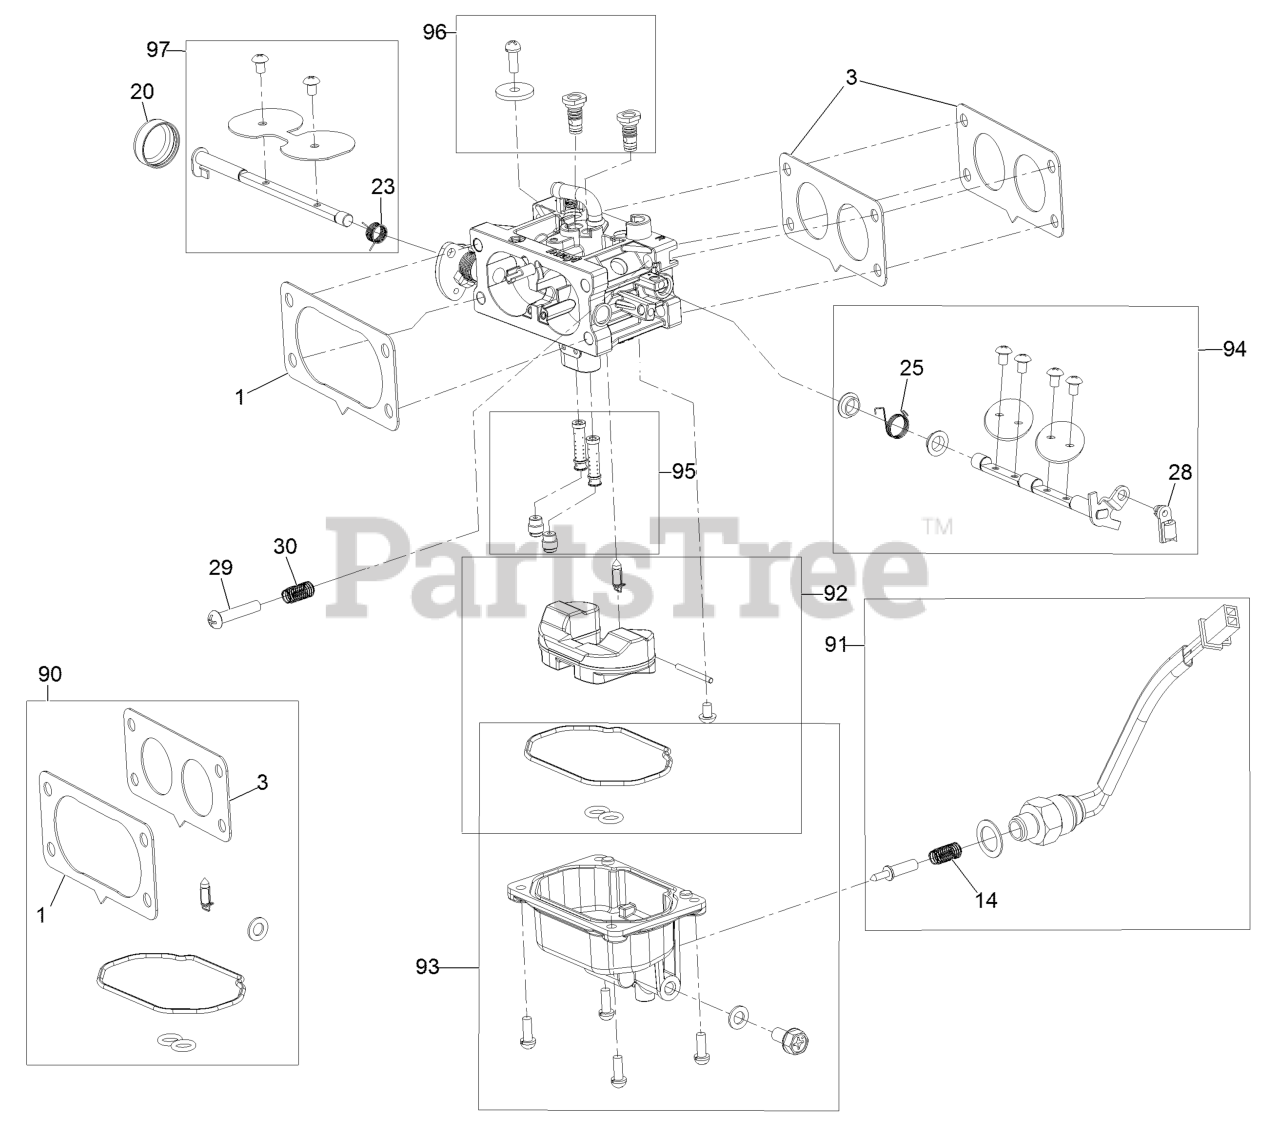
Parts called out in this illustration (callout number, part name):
1	Filter-Fuel
2	Clamp-Fuel Line
3	Line-Fuel
4	Pump-Fuel
5	Screw-HHF
6	Hose-Fuel
7	Hose-Fuel
8	Gasket-Intake
9	Screw-HHF
10	Manifold-Intake
12	Gasket-Carburetor
13	Insulator-Carburetor
14	Linkage-Throttle
96	Carburetor Replacement Kit
96:1	Carburetor
96:2	Gasket-Carburetor
96:3	Gasket-Carburetor
97	Carburetor Repair Kit
97:1	Seal, Ring
97:2	Seal, Ring
97:3	Gasket-Carburetor
97:4	Gasket-Carburetor
97:5	Needle
97:6	Gasket-Drain, Bowl
98	Solenoid Kit
98:1	Solenoid Valve
98:3	Washer
98:4	Solenoid Body
99	High Altitude Kit
